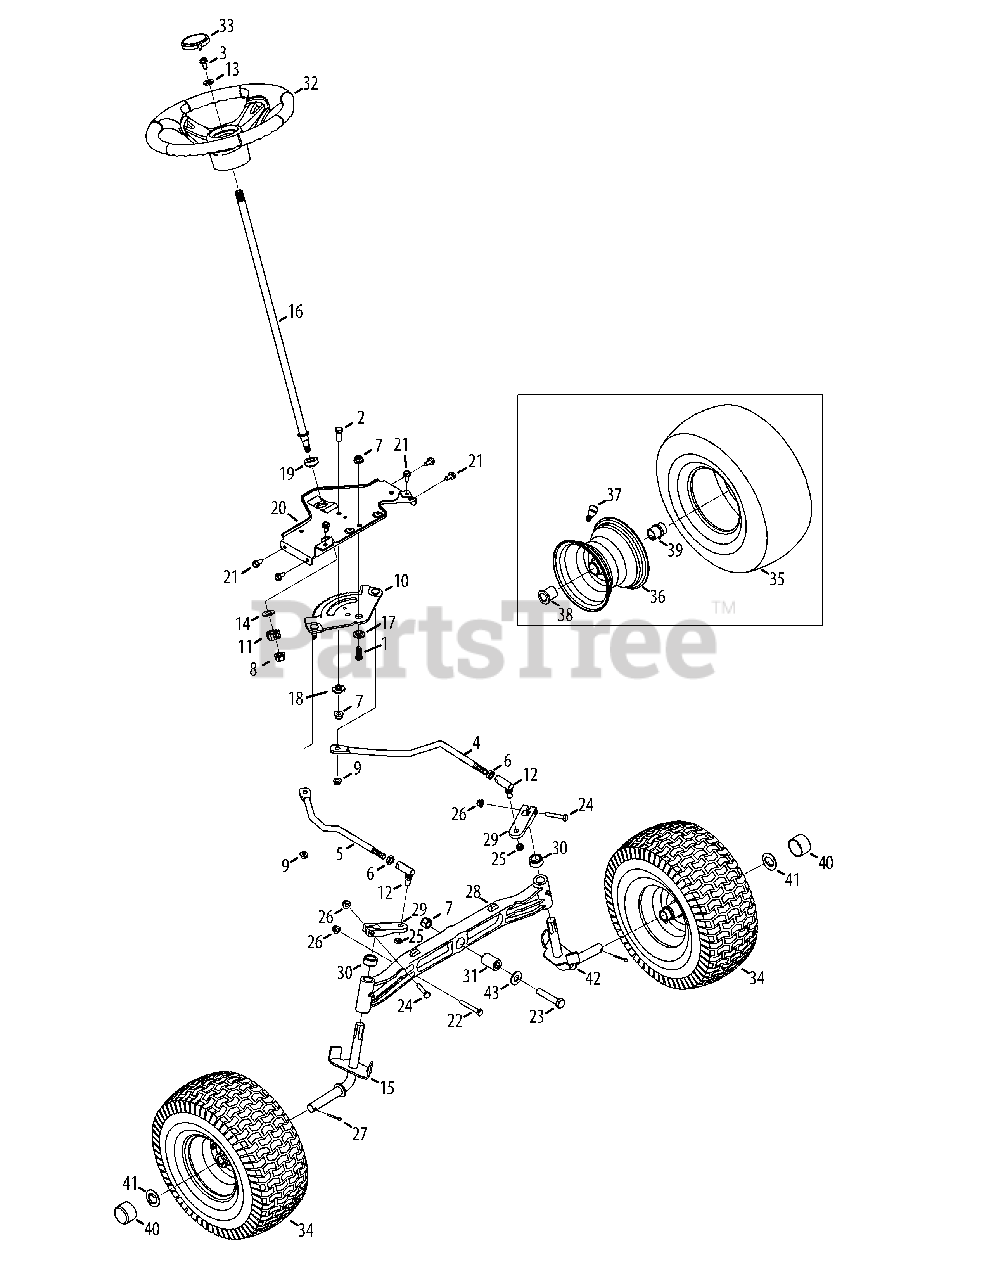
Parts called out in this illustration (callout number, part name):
1	Hex Screw, 3/8-16, 1.00, Gr5, Spec
2	Hex Screw, 3/8-16, 1.00, Gr5, Std
3	Hex Screw, 5/16-18, 1.00, Gr5, Lock
4	Link, Drag LH
5	Link, Drag RH
6	Nut, Jam, 7/16-20, Gr2
7	Nut, Flange Lock, 3/8-16, Grf,
8	Nut, Flange Lock, 7/16-20, Grb, Lock
9	Nut, Flange Lock, 5/16-18, Gr5, Sd
10	Gear, Steering, 11/90 Ratio
11	Gear, Pinion, Steering
12	Ball Joint, 7/16-20, Lock
13	Washer, Flat, .406 x .875 x .105
14	Washer, Flat, .51 x 1.12 x .06
15	Axle Ass’y, RH .750 Dia (46" Deck)
16	Shaft, Steering, .625 OD x 24.25
17	Spacer, Shoulder, .385x 1.25 x .3025
18	Spacer, .38 x 1.375, Special, 46" Only
19	Bearing, Flange, Hex 5/8 Pm
20	Bracket, Support, Steering
21	Screw, Self-tapping, 5/16-18, .750,
22	Hex Screw, 5/16-18, 2.25, Gr5, Std
23	Hex Screw, 3/8-16, 2.50, Gr5, Std
24	Hex Screw, 5/16-18, 1.75, Gr5, Std
25	Nut, Hex Lock, 3/8-24, Grb
26	Nut, Flange Lock, 5/16-18, Grf
27	Pin, Cotter, 5/32, 1.25
28	Axle, Pivot Bar, Cast
29	Steering, Block
30	Spacer, .71 ID x .125 OD x .56
31	Spacer, .385 x 1.00 x 1.5075
32	Steering Wheel, Soft Grip
33	Cap, Troy-Bilt
34	Wheel Assembly
35	Tire, 15 x 6 x 6
36	Rim Assembly, Plastic Bearing
37	Tubeless Air Valve
38	Flange Bearing, .760 x 1.00 x 1.20
39	Flange Bearing, .760 ID
40	Cap, Bumper
41	Washer, Flat, .350 x 1.559 x .062
42	Axle Ass’y, LH .750 Dia (46" Deck)
43	Washer, Flat, .406 x .875 x .059
